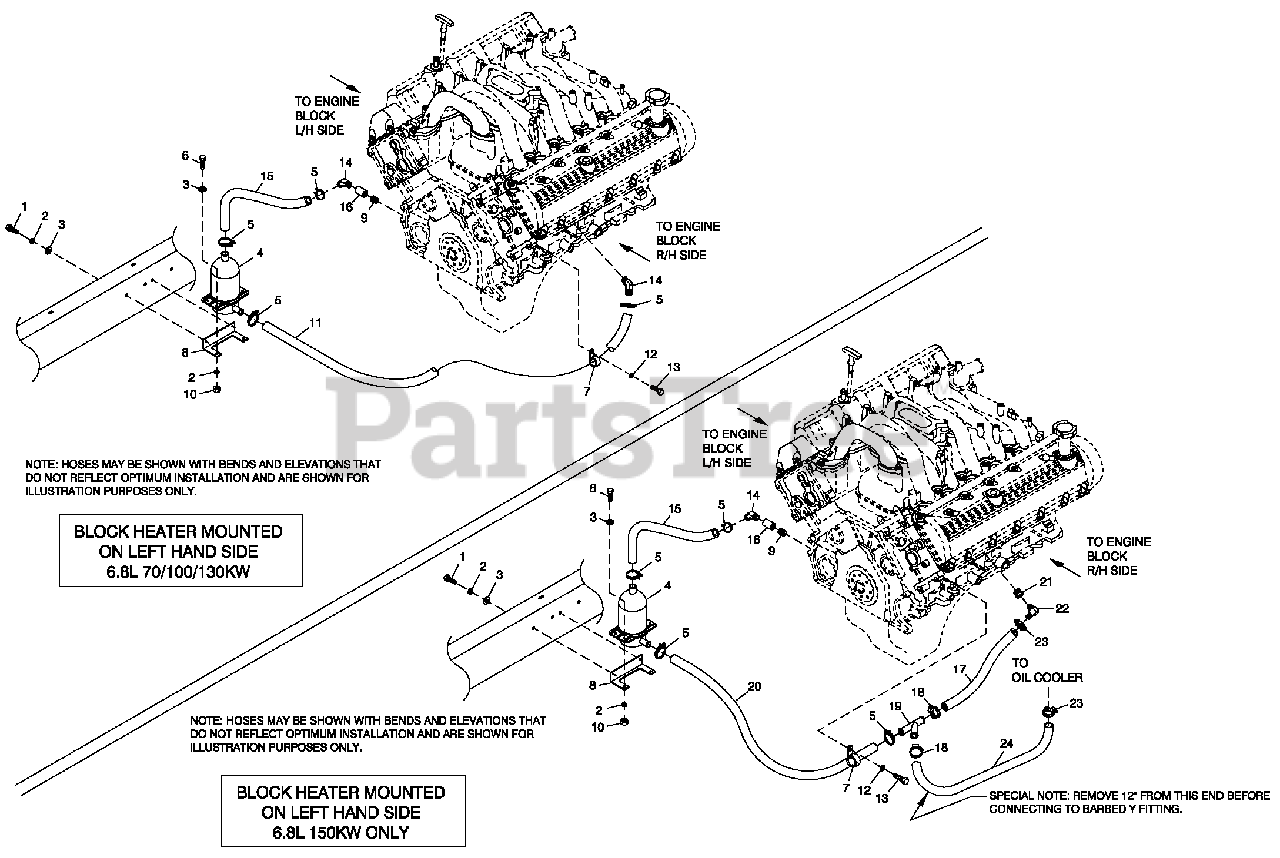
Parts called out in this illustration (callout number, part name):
1	SCREW HHC M6-1.0X 16 G8.8
2	WASHER LOCK M6-1/4
3	WASHER FLAT 1/4 ZINC
4	HEATER ENG 1500W120V
5	CLAMP HOSE 7/8" OD DOUBLE WIRE
6	SCREW HHC M6-1.0X 20 G8.8
7	CLAMP VINYL 1.06 X .4 06Z
8	BRACKET HEATER
9	NIPPLE CLOSE 3/8NPT X 1 VIBRA
10	NUT HEX M6-1.0 G8YEL CHR
11	HOSE COOL 5/8 ID 20R3 (33"LG)
12	WASHER LOCK M8-5/16
13	SCREW HHC M8-1.25 X 16 G8.8
14	BARBED EL 45 3/8NPT X 5/8OD
15	HOSE PREFORMED BLOCK HEATER
16	COUPLING FULL 3/8-18
17	HOSE 3/4 ID SAE-30R2 (8"LG) (150KW ONLY)
18	CLAMP HOSE #10.56-1.06 (150KWONLY)
19	BARB Y UNIVERSAL 5/8-3/4 HOSE (150KW ONLY)
20	HOSE COOL 5/8 ID 20R3 (24"LG) (150KW ONLY)
21	ADAPTER 1/2"NPT X 3/8"NPT (150KW ONLY)
22	BARBED EL 9 0 1/2NPT X 3/4 HOSE (150KW ONLY)
23	CLAMP HOSE #10.56-1.06 (150KWONLY)
24	HOSE OIL COOLER PREFORMED 3/4 (150KW ONLY) (SEE SPECIAL NOTE)
